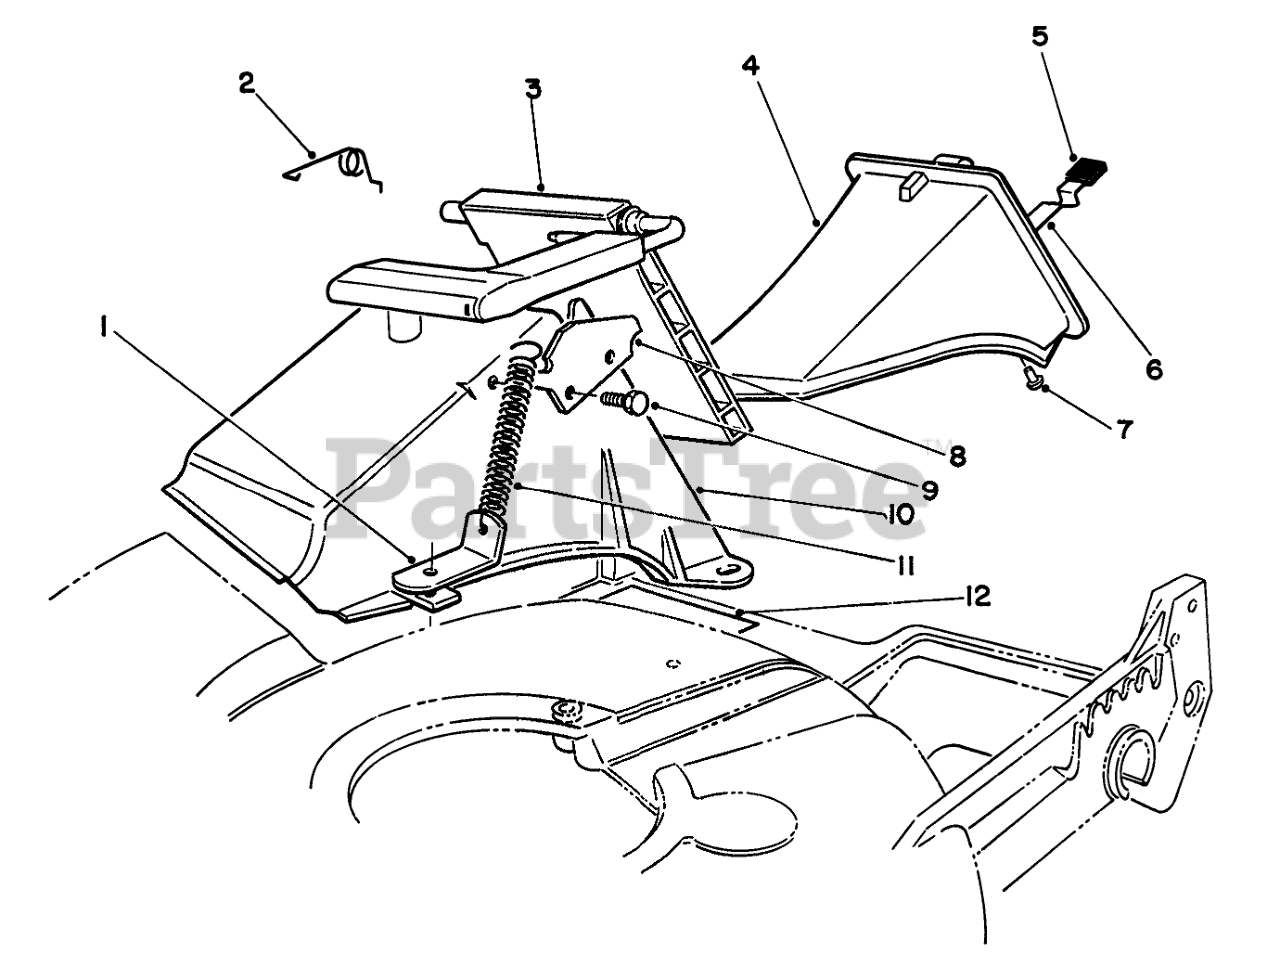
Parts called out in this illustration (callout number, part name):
1	BRACKET-SPRING
2	RETAINER-DOOR
3	DOOR ASSEMBLY
4	Plug Assembly (Incl. Ref. #5-7)
5	GRIP-LATCH
6	LATCH-PLUG, DISCHARGE
7	RIVET-HEAD, FLAT
8	DOOR LATCH PLATE
9	SCREW-PLASTITE
10	DISCHARGE TUNNEL
11	SPRING-DOOR
12	DECAL - CAUTION
